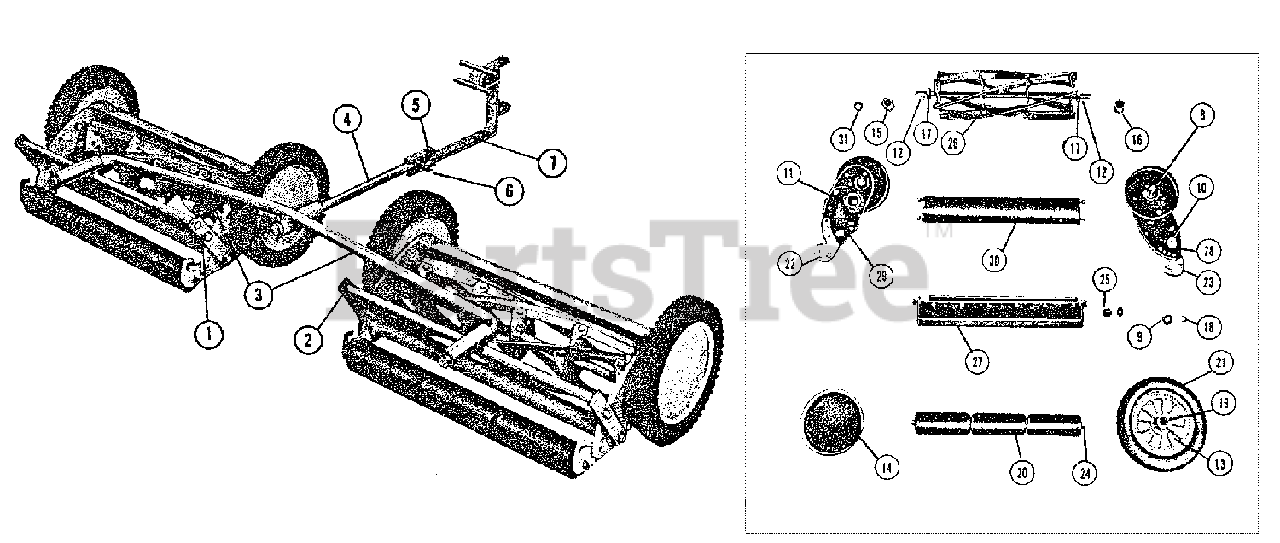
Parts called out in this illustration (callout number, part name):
1	*SINGLE DRAW BAR ASSEMBLY
2	*SINGLE DRAW BAR ASSEMBLY
3	DOUBLE DRAW BAR ASSEMBLY
4	TONGUE ASSEMBLY
5	TONGUE PIN
6	SPRING CLIP
7	FRAME EXTENSION ASSEMBLY
8	WHEEL AXLE
9	WHEEL RETAINING WASHER
10	ADJUSTING DAM
12	DRIVING PAWL
13	INTERNAL GEAR WHEEL
14	HUB CAM
15	PINION GEAR (L.H.)
16	PINION GEAR (R.H.)
17	REEL BEARING, "Nice" #1623DS
18	RING, Retainer
22	ROLLER, Retainer Bracket (L.H.)
23	ROLLER, Retainer Bracket (R.H.)
24	ROLLER SHAFT
25	HITCH BUSHING
26	REEL ASSEMBLY, 20"
27	CUTTER BAR ASSEMBLY, 20"
28	SIDE FRAME ASSEMBLY (R.H.)
29	SIDE FRAME ASSEMBLY (L.H.)
30	BRUSH BAR ASSEMBLY, 20"
31	PINION GEAR INSERT L.H.
31	PINION GEAR INSERT R.H.
